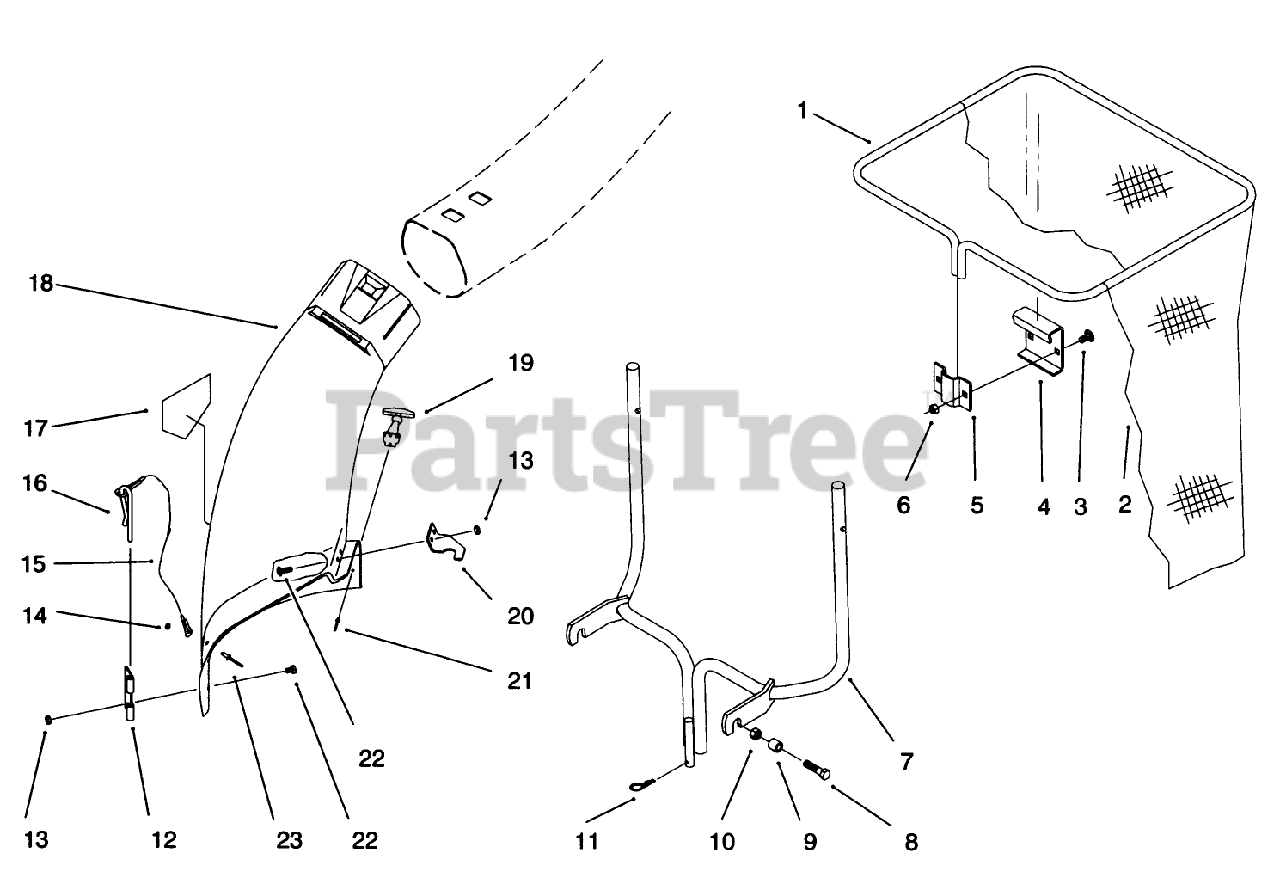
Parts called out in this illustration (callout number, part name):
2	BAG-DEPTH
3	BOLT-CARR
6	NUT-LOCK, NI
8	SCREW-HH
9	SPACER
10	NUT-LOCK, NI
11	PIN-COTTER, HAIR
12	BRACKET-MOUNTING, CHUTE
13	NUT-LOCK, NI
14	WASHER-FLAT
15	LANYARD
16	PIN-LOCKING, CHUTE
17	DECAL-DANGER
18	ASS'Y-ELBOW
20	LATCH-BAGGER ELBOW
21	RIVET-POP
22	SCREW-HEAD, TRUSS
23	RIVET-POP
